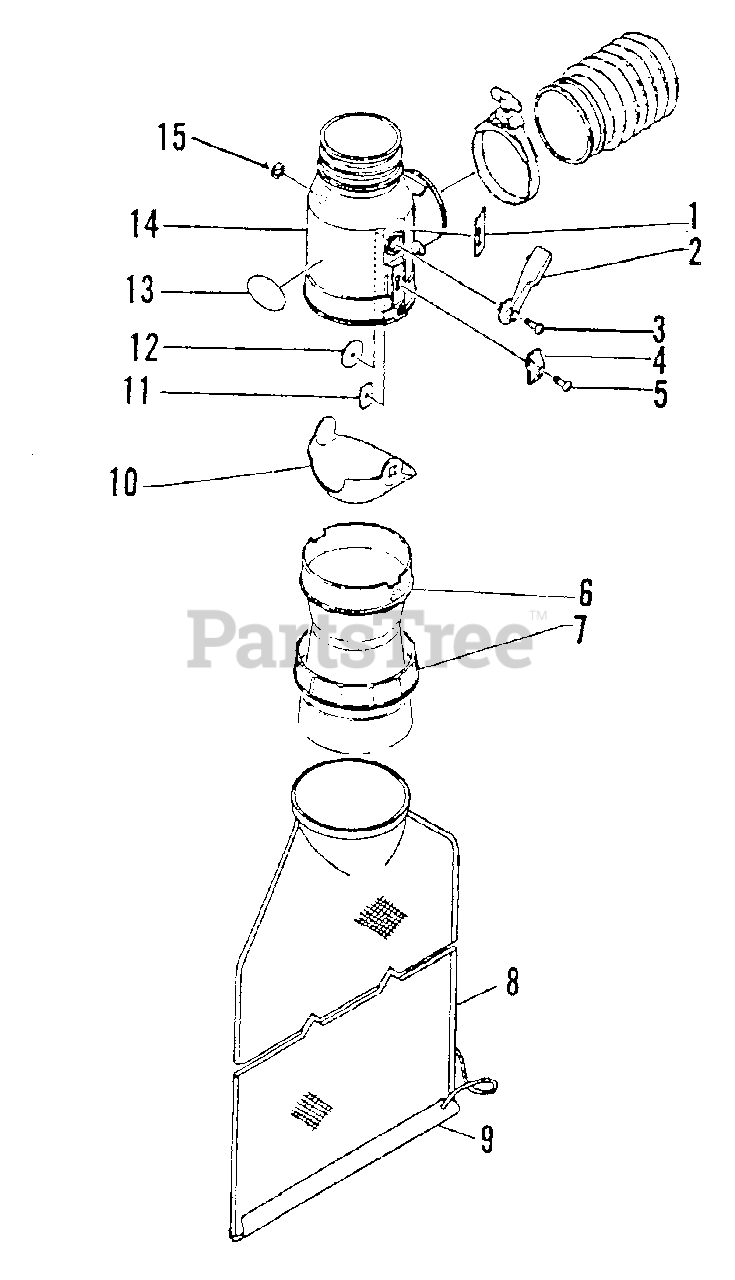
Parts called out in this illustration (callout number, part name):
3	SCREW 5×14
5	SCREW 4×14
6	CONNECTOR
8	BAG, VACUUM
9	CLIP, VACUUM BAG
13	LABEL - ECHO
14	TUBE, SUCTION
15	RING, RETAINING - 8
